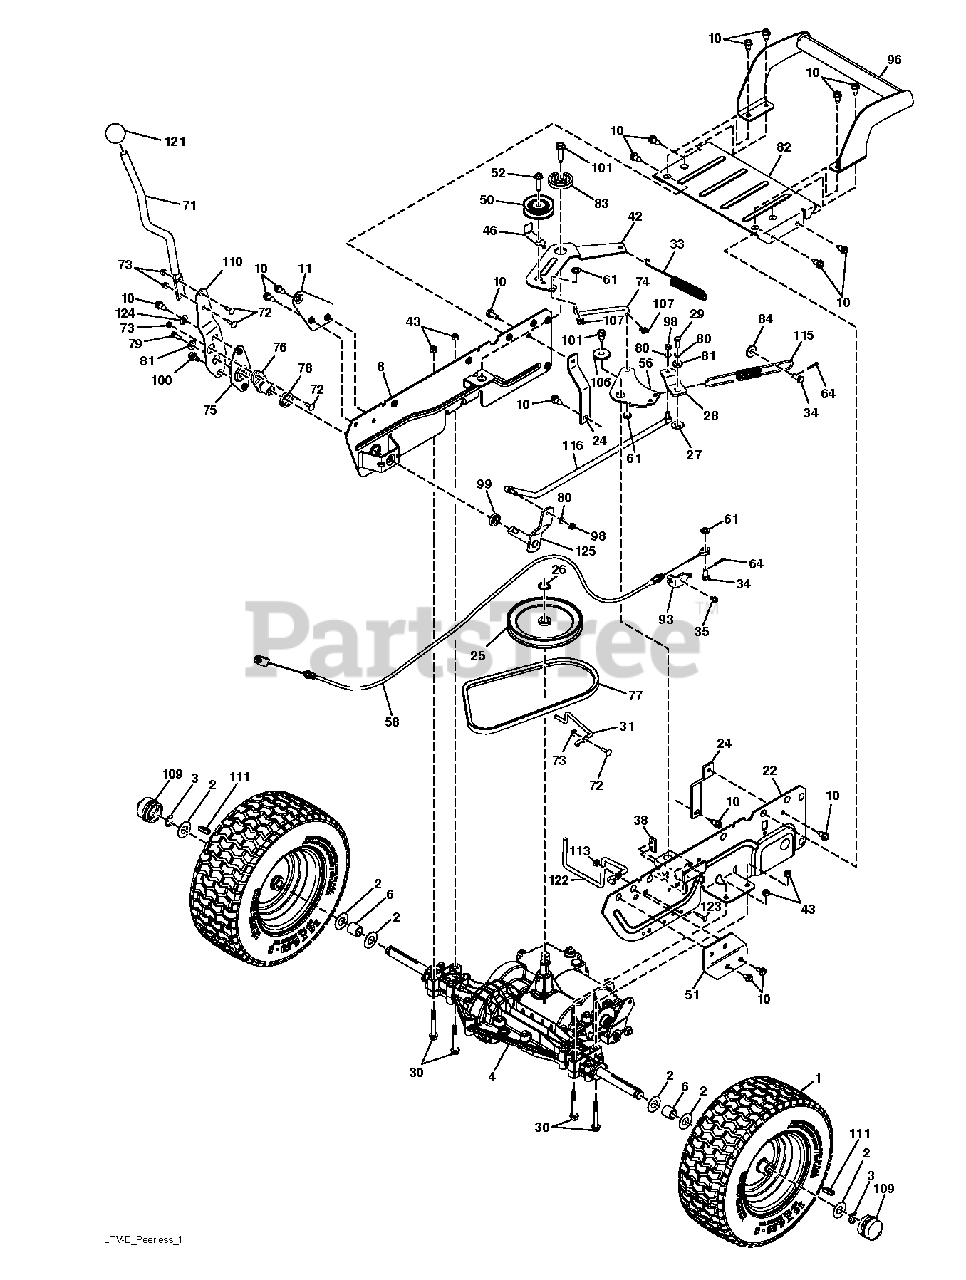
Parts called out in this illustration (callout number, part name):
1	Poulan TBD
3	E-RING LT
4	TRANSMISSION 4SPD MST 204-583A
6	SPACER, AXLE PVST
8	WELDMENT.SIDEPLATE.RH.X431
10	SCREW
11	BRACKET.SUPPORT.RH
22	WELDMENT.SIDEPLATE.LH.X431
24	STRAP.TORQUE.PMST.LRVB.PNT.431
25	PULLEY.INPUT.LRVB.PMST
26	RETAINING RING LT
27	WASH-SHFT PLT LT
28	ARM.SHIFTER.GEARDRIVE.PNT.431
29	Bolt, 1/4-20 unf Grade 8 w/Patch
31	Drive Belt Keeper, Lrvb.X431
33	Tensioner Spring
34	PIN.HEX.CROSSDRILLED.3125
35	SCREW.1/4-20X3/8
38	PLATE NUT ZTR
42	ARM.CLUTHCHING.LRVB..PNT.431
43	NUT.71038.31-18.HEX.NYLOCK
46	KEEPER.BELT.CLUTCHING.ARM.X431
50	PULLEY.V-IDLER.
51	BRACKET SUPPORT.LH
52	Bolt, 5/16-18 X 1.25
56	BELLCRANK GROUNDDRIVE.LRVB.431
58	Brake Cable, LRVB Pmst
61	WASHER
64	COTTER PIN
71	TUBE.SHIFT.LRVB
73	NUT.CROWNLOCK.1/4
74	LINK.CLUTCHING.ARM.BELLCRANK
75	MNTG BRKT. SHIFT ARM
76	HUB.SHIFT
77	Drive Belt, Ground.Lrvb.Pmst
78	SPACER.NYLON.
80	LOCKWASHER
81	WASHER LT
82	COVER.REAR.LRVB.PMSTX431
83	SPACER.RETAINER
93	BRAKE.MOUNT.CABLE.LRV
96	BUMPER.REAR.WELDMENT.BLACK.LRV
98	NUT LOCK CENTER 1/4 -28 FNTHD
99	SPACER.ARM.SHIFTER
100	BOLT.SHOULDER.5/16-18X
101	SCREW 3/8-16 X 1-1/2
106	SPACER.RETAINER
107	CLIP RETAINER
109	CAP.HUB.AXLE.LRVA/B
110	BRACKET, SHIFTER FLEX
111	SQUARE KEY
113	NUT LOCK HEX FLANGE 5/16-18
115	SPRING.BRAKE.ENGAGE.LRVB.PMST
116	LINK.STUD.BALL.GEARDRIV
121	KNOB.SHIFT.GEARDRIVE.LRVB
122	Engine Belt Keeper, LRV Gen2
123	BOLT
124	WASHER.SRRTD.5/16
125	SUBASM.SHAFT.SIFT.GEARDRVE.431
